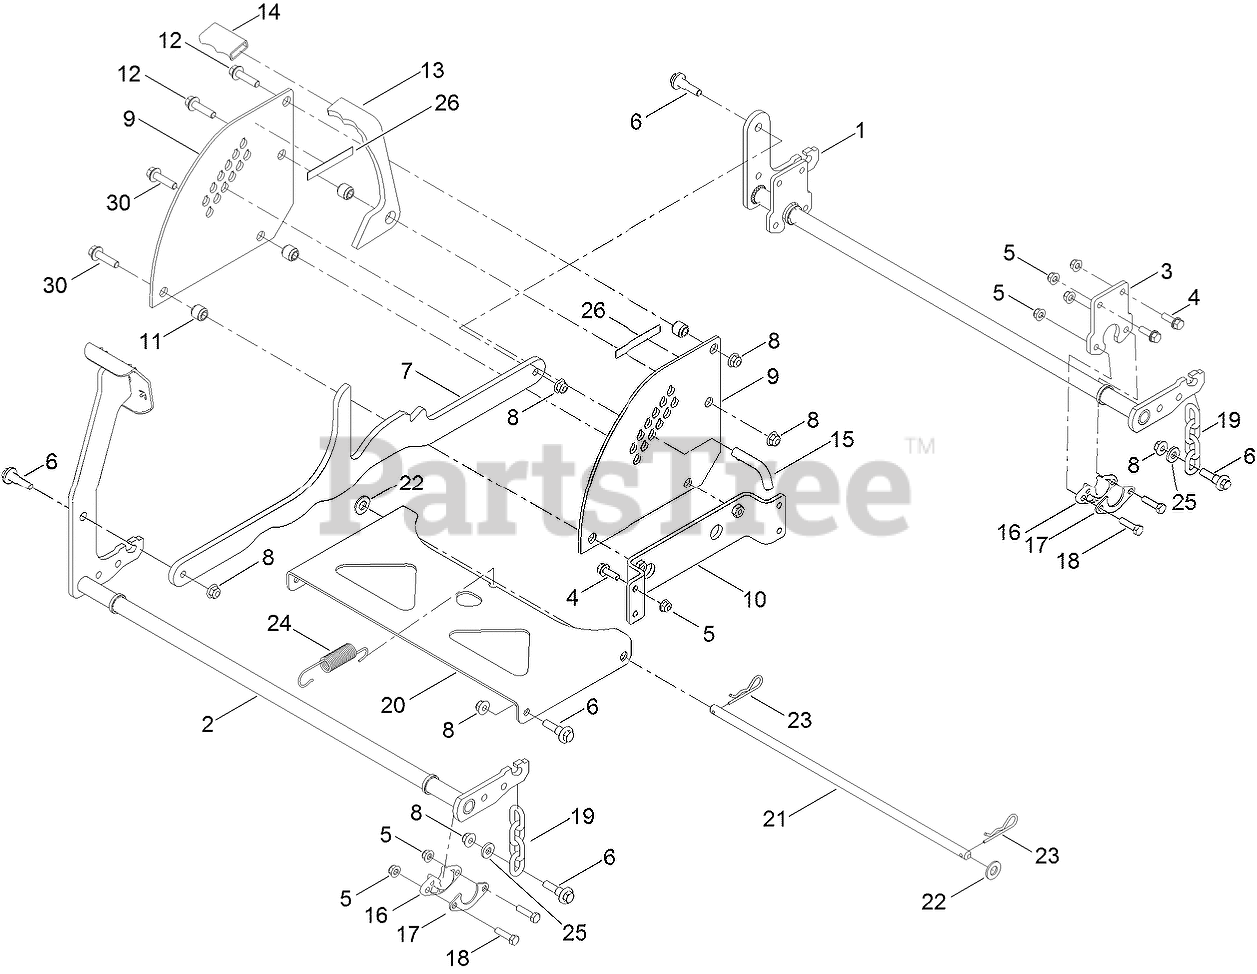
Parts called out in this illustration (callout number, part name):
1	PIVOT-REAR
2	PIVOT-FRONT
4	SCREW-HHF
5	NUT-HF
6	BOLT-SHOULDER
7	LINK-HOC
8	NUT-HF, NI
9	PLATE-DECK, LIFT
10	PLATE-LIFT
11	SPACER-DOUBLE STEP
12	SCREW-HHF
13	TRANSPORT LOCK-HOC
14	GRIP-FLAT
15	PIN-HOC
16	BUSHING-FLANGE
17	GUSSET-DECK LIFT
18	SCREW-HH
19	CHAIN-DECKLIFT, 4-LINK
20	PAN-PIVOT, DECK
21	ROD-PIVOT, DECK
22	WASHER-FLAT
23	PIN-HAIR
24	SPRING-EXTENSION
25	SPACER-HUB, BLOWER
26	PAD-RUBBER
30	SCREW-HHF
